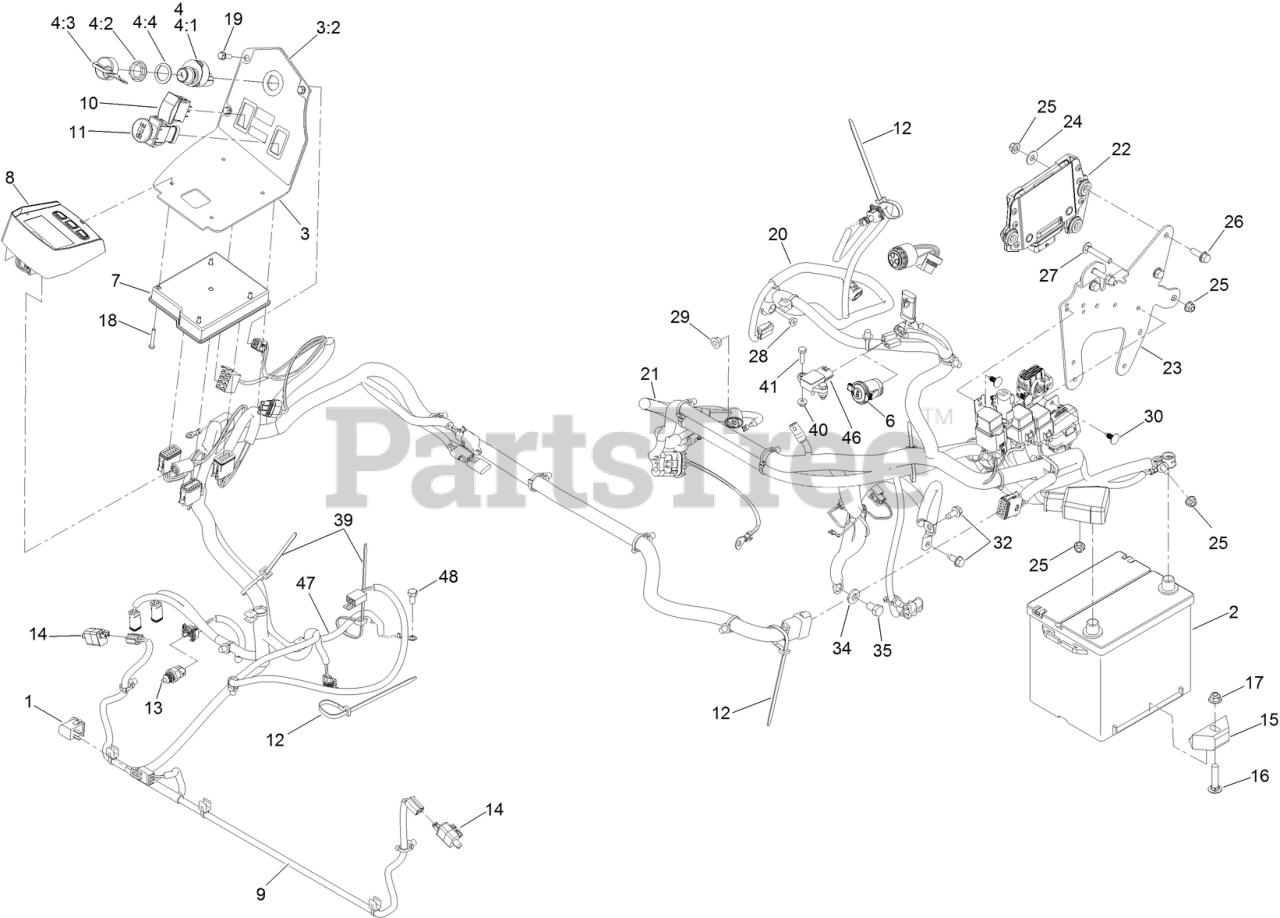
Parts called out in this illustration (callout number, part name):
1	SWITCH-BAIL
2	BATTERY-DRY
3	CONSOLE ASM
3:2	DECAL-CONTROL PANEL
4	IGNITION SWITCH ASM
4:1	HUB and BEARING ASM
4:2	NUT-MOUNTING
4:3	IGNITION KEY SET
4:4	WASHER-BACKUP
6	PORT-POWER, 12V
7	MODULE-MCU
8	MODULE-HORIZON
9	HARNESS-WIRE
10	SWITCH
11	SWITCH-PTO, SEALED
12	TIE-PLASTIC
13	SENSOR-TEMPERATURE
14	SWITCH
15	RETAINER-BATTERY
16	SCREW-CARR
17	NUT-HF, NI
18	SCREW-PPH
19	SCREW-HWH
20	HARNESS-WIRE
21	CABLE-BATTERY
22	SEE 135-4281 (SERVICE ASM)
23	BRACKET-MOUNT, ECU
24	WASHER-FLAT
25	NUT-HF, NI
26	SCREW-HHF
27	BOLT-CARR
28	NUT-HF
29	NUT-HF
30	PLUG-PLASTIC
32	SCREW-HWHTF
34	WASHER-BELLEVILLE
35	SCREW-HH
39	TIE-CABLE
40	NUT-HF
41	SCREW-HH
46	SENSOR-ATM
47	HARNESS-WIRE, JUMPER
48	BOLT
